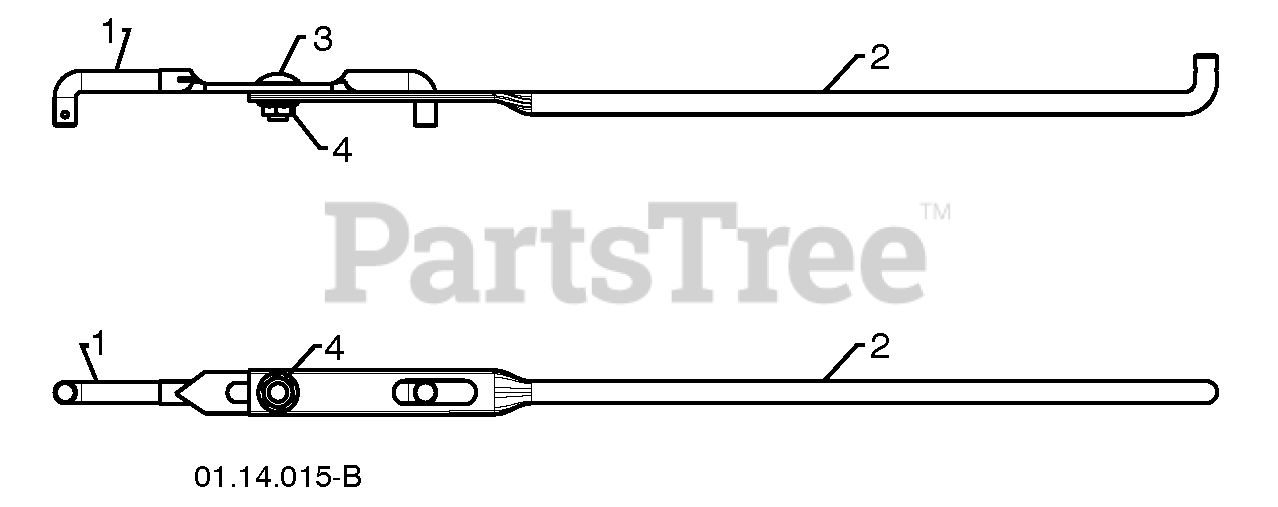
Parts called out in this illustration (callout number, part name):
1	ROD.SHIFTER.TOP.HYD
2	ROD, LOWER, SPEED CONTROL
3	BOLT
4	NUT.FLANGE.5/16
